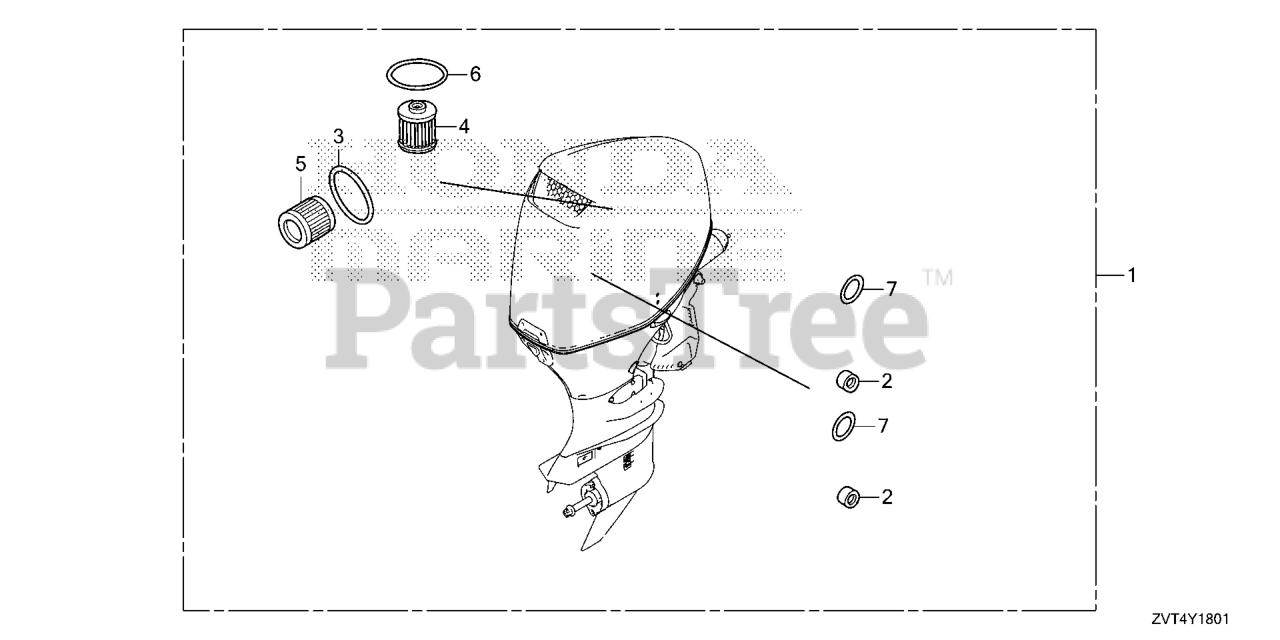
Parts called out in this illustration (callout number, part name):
1	KIT (400)
2	METAL, ANODE
3	O-RING
4	FILTER, FUEL
5	SCREEN, FUEL STRAINER
6	O-RING
7	O-RING (37X2.4)
